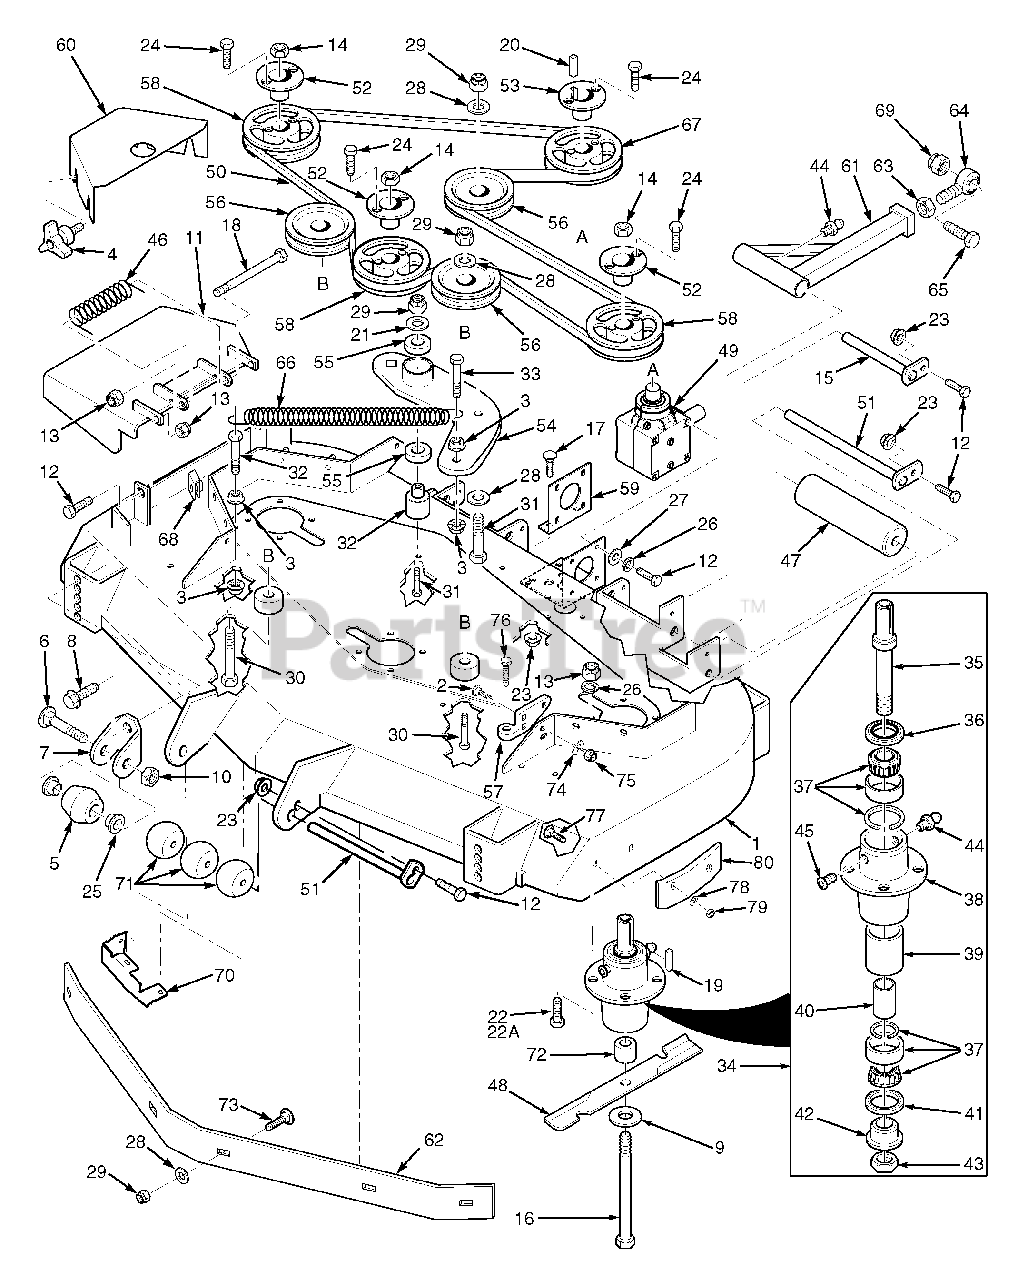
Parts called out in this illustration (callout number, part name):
1	Cutter Deck, 72" Advantage
2	Bolt, Carriage 7/16-14 x 1-1/4"
3	Nut, Hex Serrated Flange 3/8-16
4	Wing Nut, 3/8-16
5	Anti-Scalp Wheel
6	Bolt, Carriage 3/8-16 x 4"
7	Anti-Scalp Wheel Bracket
8	Bolt, Hex Serrated Flange 3/8-16 x 1"
9	Flatwasher, 5/8" Hardened
10	Locknut, 3/8-16 Center Lock
11	Discharge Chute, 72" Adv.
12	Bolt, Hex Head 5/16-18 x 1.75" - Front
13	Nut, Hex Elastic Stop 5/16-18 Grade 8
14	Nut, 5/8-11 UNC
15	Push Arm Shaft
16	Bolt, Hex Head 5/8-11 x 9.50"
17	Bolt, Carriage 5/16-18 x .75"
18	Bolt, Hex Head 5/16-18 x 4.75"
19	Key, 1/4 x 1/4 x 2"
20	Key, 1/4 x 1/4 x 1.25"
21	Flatwasher,3/8-.39 x .938 x .105 HD
22	Bolt, Hex Head 5/16-18 x 1-3/4"
23	Nut, Hex Serrated Flange 5/16-18
24	Bolt, Hex Head 1/4-20 x 1" Grade 8
25	Bushing, .376 I.D. Oilite
26	Lockwasher, 5/16"
27	Flatwasher, 5/16" (.375 x .875 x .083)
28	Flatwasher, 3/8" (.391 x .938 x .105)
29	Nut, Hex Elastic Stop 3/8-16
30	Bolt, Hex Head 3/8-16 x 3-1/4"
31	Bolt, Hex Head 3/8-16 x 3"
32	Pivot, Idler - Short
33	Bolt, Hex Head 3/8-16 x 1.50" Grade 8
34	Spindle Assembly
35	Spindle Shaft
36	Seal, Top
37	Bearing Assembly
38	Spindle Housing
39	Spacer, Outside
40	Spacer, Inside
41	Seal, Bottom
42	Spindle Bushing, Bottom
43	Nut, Special 1 - 1/16-18
44	Grease Fitting
45	Relief Fitting, Tapered Spindle
46	Spring, Discharge Chute
47	Guide, Roller
48	Cutter Blade, 24.5" 72"
49	Gearbox Assembly, Deck Drive
50	Belt, Cutter Deck Drive, 72"
51	Roller Shaft
52	Tapered Hub, 1-1/8" Bore
53	Tapered Hub, 1" Bore
54	Idler Arm, Cutter Deck
55	Bearings, Ball
56	Pulley, Idler
57	Lever Assembly, Deck Level
58	Pulley, 6.95 O.D. - 72"
59	Mounting Plate, Gearbox
60	Belt Cover, LH - 72"
61	Pusharm
62	Baffle, Custom Cut 72A
63	Nut, Hex Head 5/8-18 UNF
64	Rod End, 5/8" Male RH Thread
65	Bolt, Hex Head 5/8-11 x 4-1/2"
66	Spring, Cutter Deck
67	Pulley, 6.35 O.D. - 72"
68	U-Nut, 3/8-16
69	Nut, Hex Elastic Stop 5/8-11
70	Discharge Baffle 72"
71	Wheel, Anti-Scalp
72	Spacer, Spindle Bottom
73	Bolt, Carriage 3/8-16 x 1"
74	Flatwasher, 7/16-.500 x 1.25 x .083
75	Nut, Elastic Stop 7/16-14
76	Bolt, Deck Adjust
77	Bolt, Carraige 5/16-18 x 3/4"
78	Flatwasher, 5/16"
79	Nut, Center Lock 5/16-18
80	Wear Pad
04001.11	Bolt, Hex Head 5/16-18 x 1.50" - Rear
